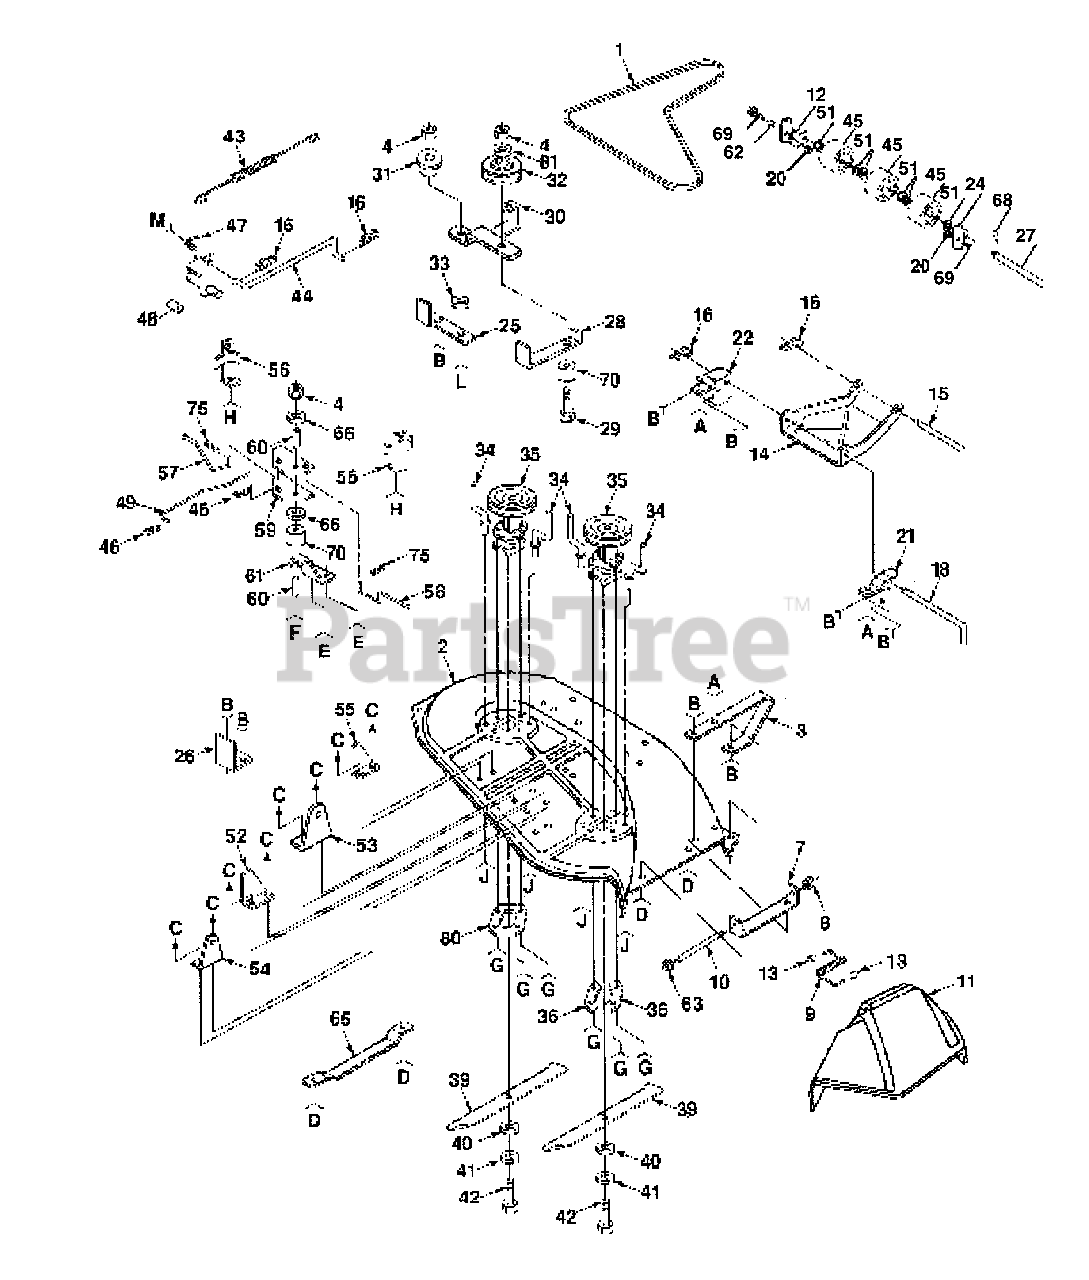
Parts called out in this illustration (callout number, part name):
2	Housing
3	Runner R:H.
4	Locknut 3/8 - 16
7	Bracket, Deflector
9	Spring, Deflector
10	Rod, Hinge
11	Deflector, Shield
12	Bracket, Nose Roller L.H.
14	Link, Parallel
15	Pin, Hinge, Front
16	Spring, Retainer
18	Pin, Hinge, Rear
20	Locknut 5/16 - 18
21	Bracket, Lift R.H.
22	Bracket, Lift L.H.
24	Bracket, Nose Roller R.H
25	Support, Arm
26	Stop, Deck, Front
27	Pin, Pivot
28	Guide, Belt
29	Bolt 3/8 - 16 x 2
30	Arm, Idler Assembly
32	Pulley, Idler
33	Washer, Wear 1/16
34	Keeper, Belt
35	Mandrel, Assembly
36	Plate, Support, Mandrel
39	Blade
40	Washer 13/32 x 1 - 1/4 x 12 Ga.
41	Washer, Lock 3/8
42	Bolt, Hex 3/8 - 24 x 1 -1/2 Gr. 5
43	Spring, Ext.
44	Rod, Clutch, Mower
45	Roller, Nose
46	Pin, Cotter 3/16 x 1
47	Assembly, Rock Shaft
48	Spacer 1 /2 x 9/16
49	Rod, Brake, Primary
51	Washer 15/32 x 1 x 10 Ga.
52	Bracket, Pivot R .H.
53	Bracket, Pivot L.H.
54	Bracket, Susp., Rear R.H.
55	Bracket, Susp., Rear L.H.
56	Brake Assembly
57	Rod, Brake, Secondary L.H.
58	Rod, Brake, Secondary R.H.
59	Bracket, Brake, Pivot
60	Spacer, Brake
61	Bracket, Support
62	Washer 1/2 x 1 x 16 Ga.
63	Washer 11/32 x 5/8 x 16 Ga.
65	Runner L.H.
66	Washer 13/32 x 1 x 14 Ga
68	Pin, Cotter 1/8 x 3/4
69	Bolt, Hex Hd. 5/16 - 18 UNC x 3/4
75	Pin, Cotter 3/32 x 1/2
80	Plate, Support L.H
81	Washer, 13/32 x 13/16 x 16 Ga.
